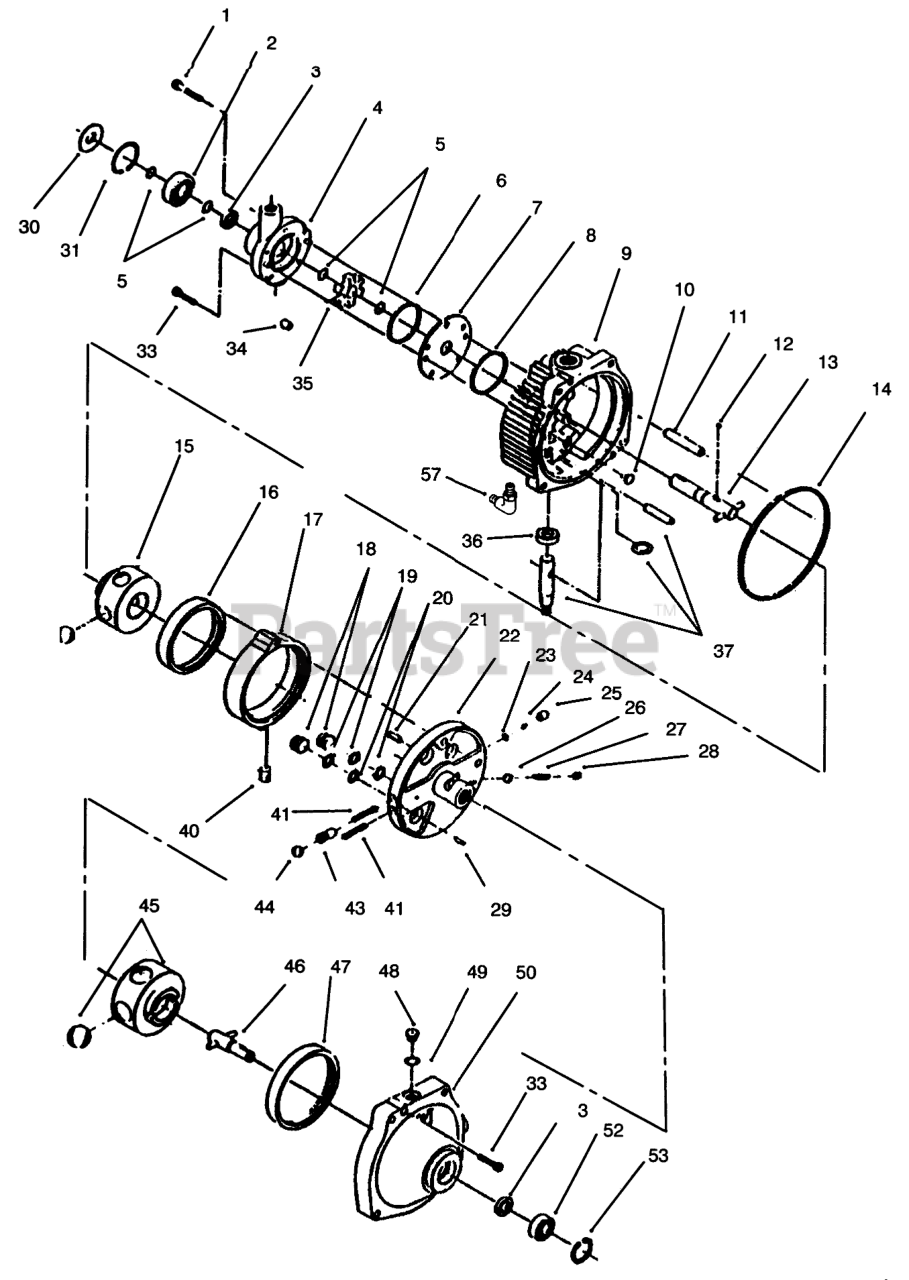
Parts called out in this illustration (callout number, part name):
1	CAPSCREW
2	BEARING
3	SEAL-OIL
4	Housing-Pump Assembly (Incl. Ref. #3)
7	PLATE
9	Cover Assembly (Incl. Ref. #11, 36 & 37)
10	BUTTON
13	SHAFT
15	ROTOR
16	PUMP-RACE
17	RING-CAM
18	PISTON
20	O-RING
22	Pintle Assembly (Inc. Ref. #1, 18-21, 23-29 41, 43 & 44)
27	SPRING
30	SHIELD-GRASS
31	RETAINING-RING
33	SCREW-HH
35	CARRIER
36	SEAL-OIL
37	SHAFT KIT
40	INSERT
41	SPRING
45	ROTOR
46	SHAFT
48	Plug-Asm (Incl. Ref. #49)
49	O-RING
52	Bearing-Output
56	Ring-Cam (Incl. Ref. #16-17)
57	FITTING-HYDRAULIC 90 DEG
